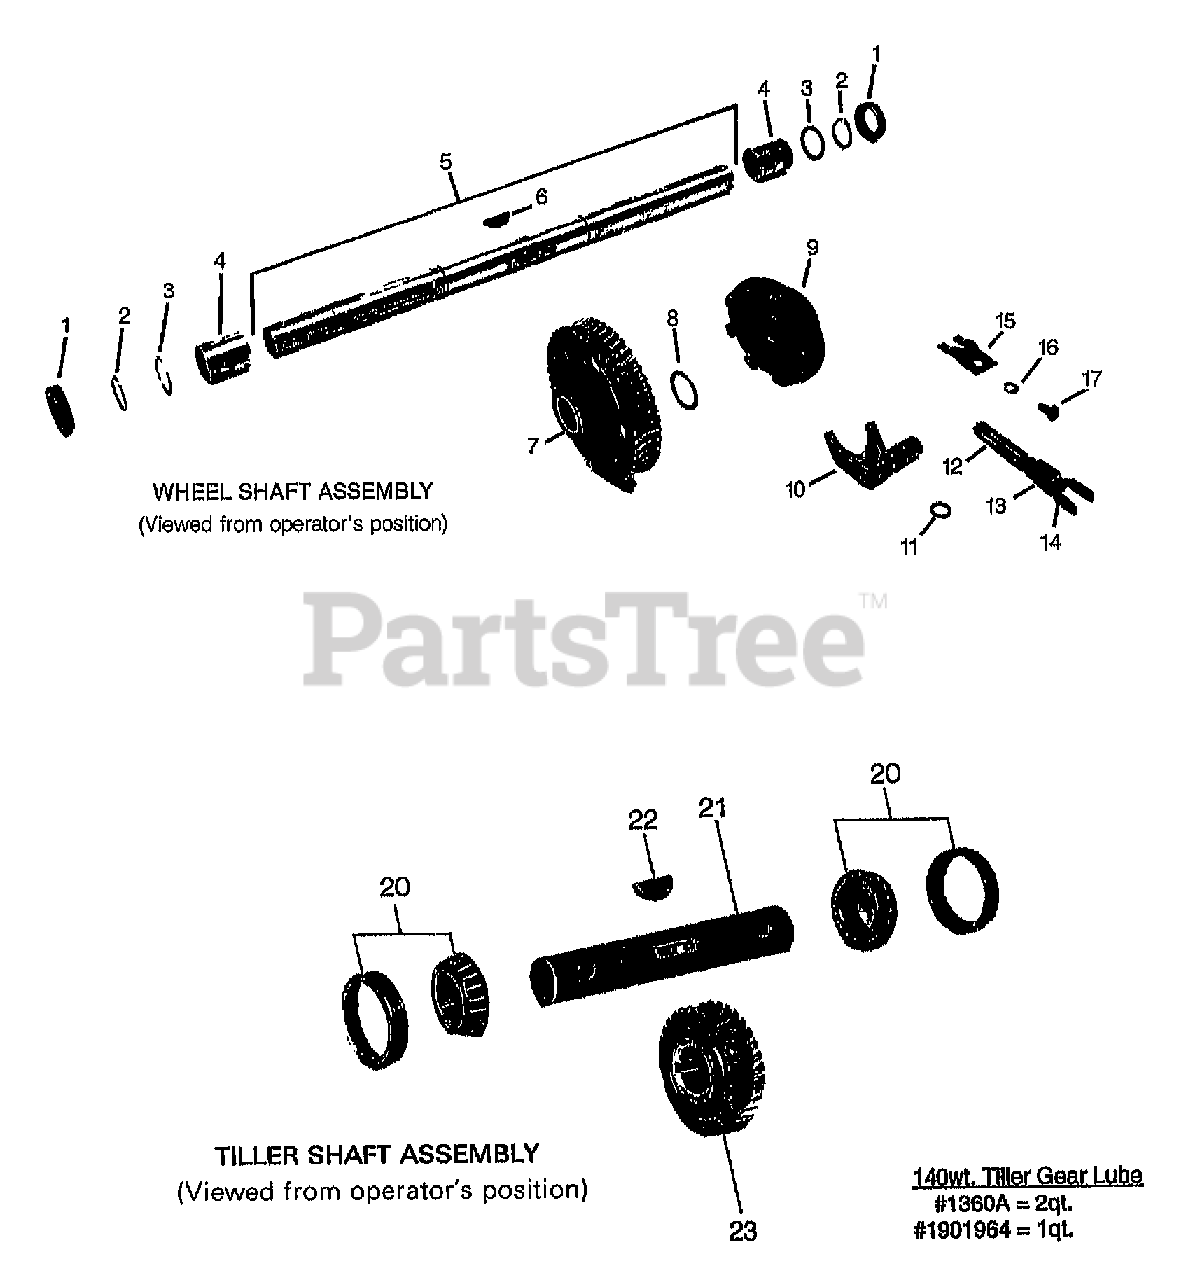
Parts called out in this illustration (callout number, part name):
1	OIL SEAL--LEFT AND RIGHT SIDES
2	RING--RETAINING, HEAVY-DUTY,EXTERNAL
3	SHIM--1 1/64"I.D.,0.062" THICK
3	SHIM--AS ABOVE, ONLY 0.030" THICK
3	SHIM--AS ABOVE, ONLY 0.015" THICK
3	SHIM--AS ABOVE, ONLY 0.010" THICK
4	BUSHING--
5	WHEEL SHAFT--(INCL.#9305 KEY)
6	KEY--HI-PRO, 1/4"X1", CLUTCH TO WHEEL SHAFT
7	GEAR--WHEEL DRIVE(WORM GEAR), CAST IRON
8	SHIM--BETWEEN KEY AND GEAR, 1.016"I.D.X1. 468" O.D.X.062" THICK
9	CLUTCH--WHEEL DRIVE, CAST IRON
10	YOKE--CLUTCH SHIFTING "O" RING--YOKE SHAFT,
11	OIL SEAL, FITS IN GROVE CLOSEST TO YOKE
12	PINION--FOR CLUTCH YOKE
13	PIN-SPIRAL, 3/16" DIAMETER X 7/8" LONG
14	UNIVERSAL--FOR CLUTCH FORK PINION
15	PLATE-FRICTION
16	LOCKWASHER--1/4"
17	BOLT--HEX HEAD, 1/4"-20X1/2"
20	BEARING--TAPERED ROLLER, WITH CUP (RACE), TILLER SHAFT, LEFT AND RIGHT SIDES
21	TILLER SHAFT, WITH #1104 KEY IT-TILLER GEAR PONY 1-4
22	KEY--WOODRUFF, 1/4" X 1 1/4", TILLER SHAFT /WORM GEAR
23	WORM GEAR--BRONZE, TILLER DRIVE
